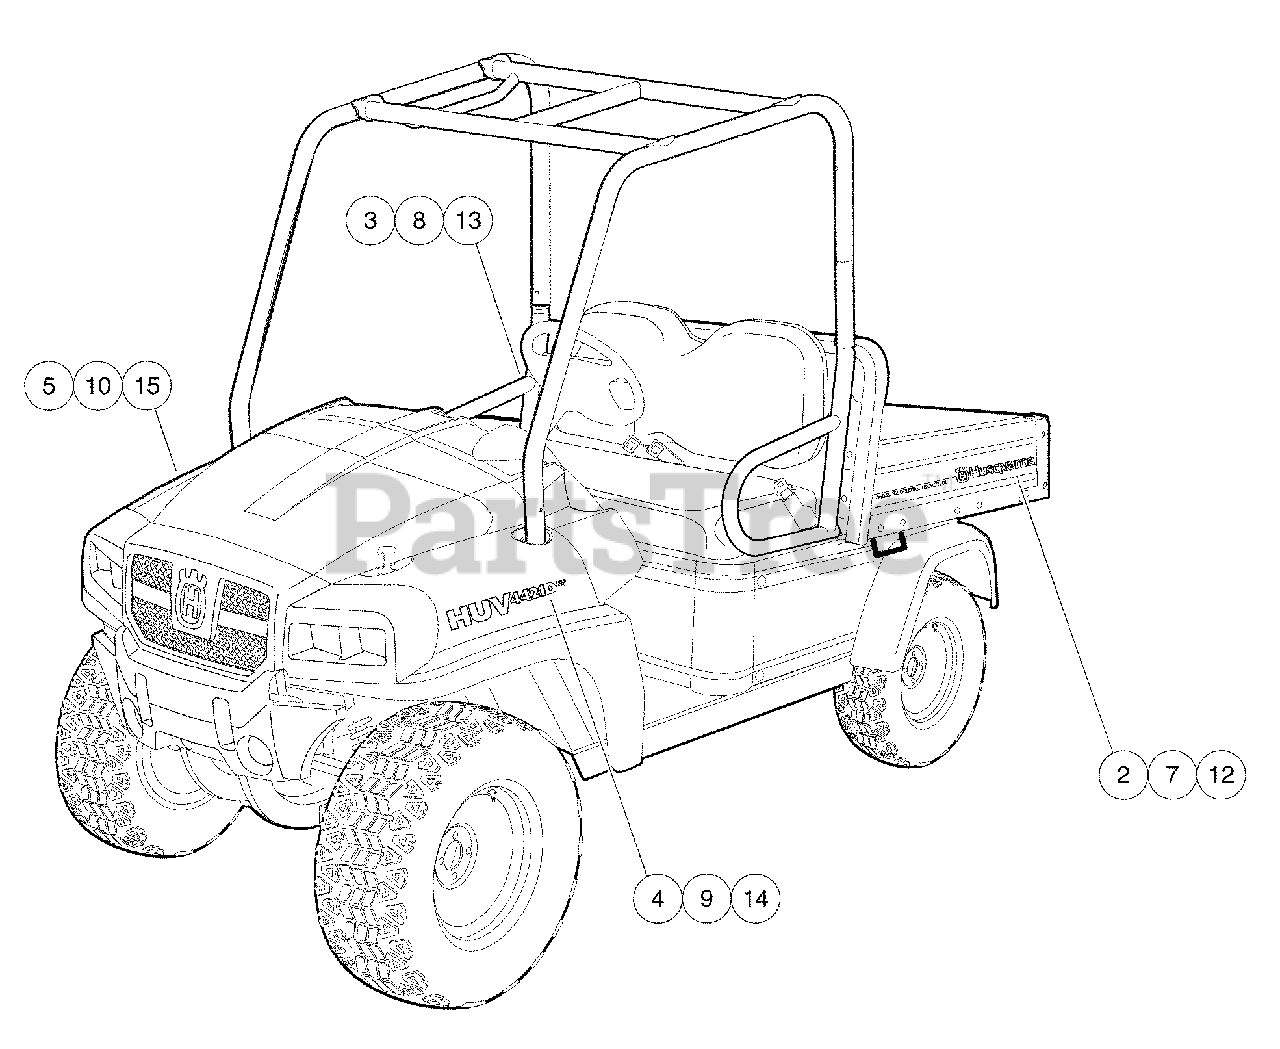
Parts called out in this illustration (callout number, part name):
2	Decal, Bed, Huv, Moff, Ds
3	Decal, Bed, Huv, Moff, Ps
4	Decal, Huv, 4421dxp, Moff, Ds
5	Decal, Huv, 4421dxp, Moff, Ps
7	Decal, Bed, Huv, Orange, Ds
8	Decal, Bed, Huv, Orange, Ps
9	Decal,huv 4421dxp, Orange, Ds.
10	Decal,huv 4421dxp, Orange, Ps.
11	Instl,decal,huv4421dxp,olv Grn
12	Decal, Bed, Huv, Olv Grn, Ds
13	Decal, Bed, Huv, Olv Grn, Ps
14	Decal,huv 4421dxp, Olv Grn, Ds
15	Decal,huv 4421dxp, Olv Grn, Ps
